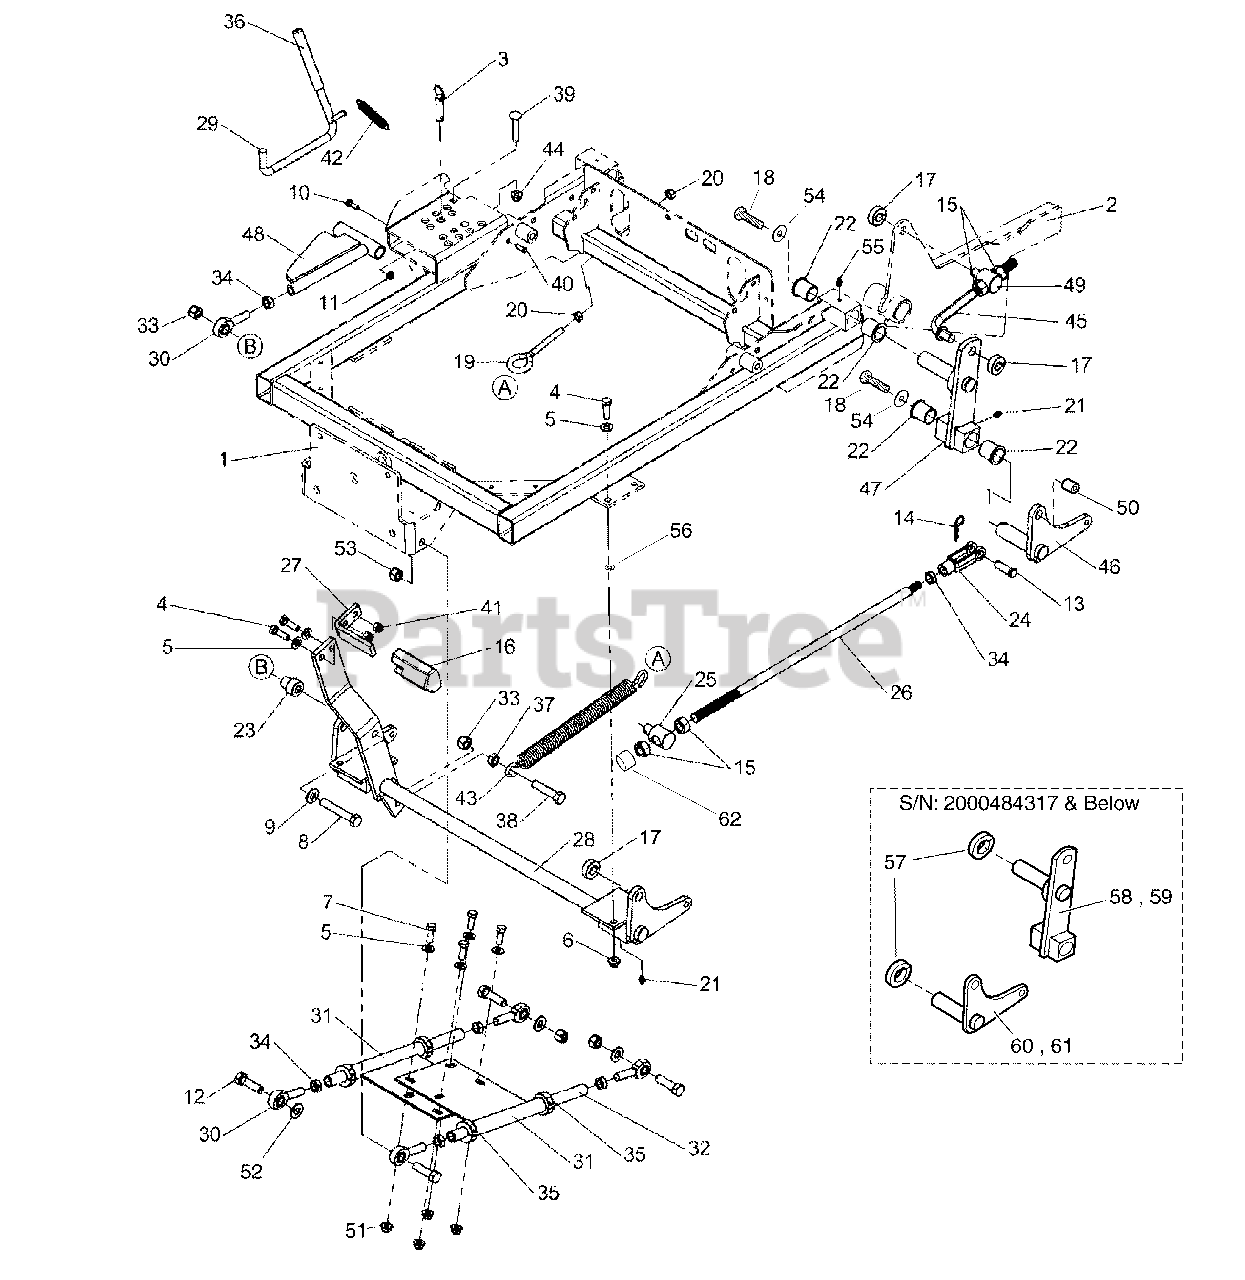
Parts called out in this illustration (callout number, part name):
1	MAIN FRAME
2	MOTOR MOUNT
3	HITCH PIN, 1/2 X 2"
4	BOLT, 3/8-16 X 1-1/4"
5	WASHER, 3/8 GR. 9 FLAT
6	NUT, 3/8-16 Hex Nylock Flange
7	BOLT, 3/8-16 X 1"
8	BOLT, 1/2-13 X 3"
9	WASHER, 1/2" SAE
10	BOLT,1/4-20X5/8
11	NUT, 1/4-20 Hex Serrated Flange
12	BOLT, 1/2-20 X 1-3/4"
13	CLEVIS PIN, 1/2" X 1-1/2"
14	HAIR PIN CLIP
15	NUT, 5/8-11 HEX
16	RUBBER, FOOT PEDAL
17	COLLAR, 5/8" Split
18	BOLT, 3/8-16X3/4 WITH PATCH
19	EYE BOLT, 3/8-16 X 6"
20	NUT, 3/8-16 Hex
21	GREASE FITTING
22	BUSHING, Flange
23	ADAPTER, CASTER AXLE
24	CLEVIS , 1/2-20, STEEL
25	SPRING ROD PIVOT
26	DECK ADJUSTMENT ROD
27	PEDAL, FOOT - BLK
28	DECK LIFT SHAFT
29	WELD, ROD DECK LIFT - BLK
30	BALL JOINT, 1/2-20 Male
31	DECK STABILIZER
32	DECK STABILIZER SHAFT
33	NUT, 1/2-13 Hex Nylon Lock
34	NUT, 1/2-20 Hex Jam
35	COLLAR, 3/4" Split
37	NUT, 1/2-13 Hex Jam
38	BOLT, 1/2-13 X 2-1/4"
39	CARRIAGE BOLT, 3/8-16 X 2"
40	CLEVIS PIN, 1/4" x 3/4"
41	NUT, 3/8-16 Hex Nylon Lock
42	SPRING, Extension
43	DECK LIFT SPRING
44	NUT, 3/8"-16 SIDE LOCK
45	DECK LIFT ROD
46	DECK LIFT PIVOT, LH
46	DECK LIFT PIVOT, RH
47	ASSM, REAR LIFT - LH - CITATION
47	REAR DECK LIFT, RH
48	DECK ADJUST LINK
49	SPRING ROD PIVOT
50	BUSHING, .510 X .625 X .500
51	NUT, 3/8"-16 SERRATED FLANGE
52	WASHER, 1/2" GR. 9 FLAT
53	NUT, 1/2"-20 NYLON LOCK
54	FLAT WASHER, THICK
55	GREASE FITTING 45
56	WASHER, 3/8" SAE
57	COLLAR, 1" SPLIT
58	WELD, REAR LIFT, LH - ORG
59	WELD, REAR LIFT, RH - ORG
60	WELD, PIVOT, DECK LIFT - LH - ORG
61	WELD, PIVOT, DECK LIFT - RH - ORG
62	CAP, BLACK VINYL
